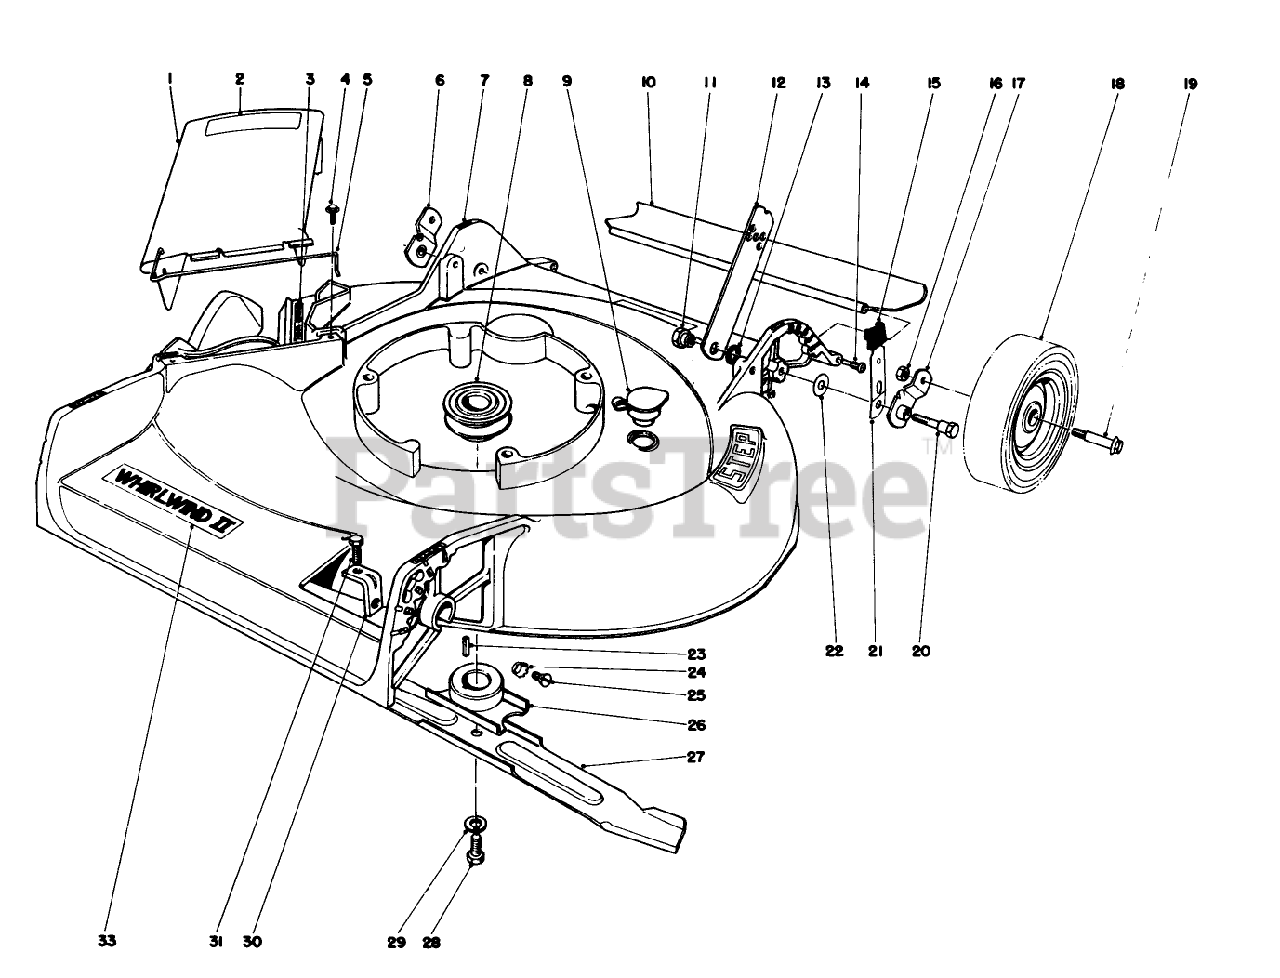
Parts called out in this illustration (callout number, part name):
4	SCREW
9	Plug Washout
10	Rear Shield
11	HANDLE PIVOT NUT
12	HANDLE LATCH
13	HANDLE LATCH SPACER
15	KNOB-ARM
20	PIVOT SCREW
21	SPRING ARM ASM
22	Washer
23	Key Square
25	SCREW-FH, S
29	WASHER-LOCK
31	SCREW-HH
